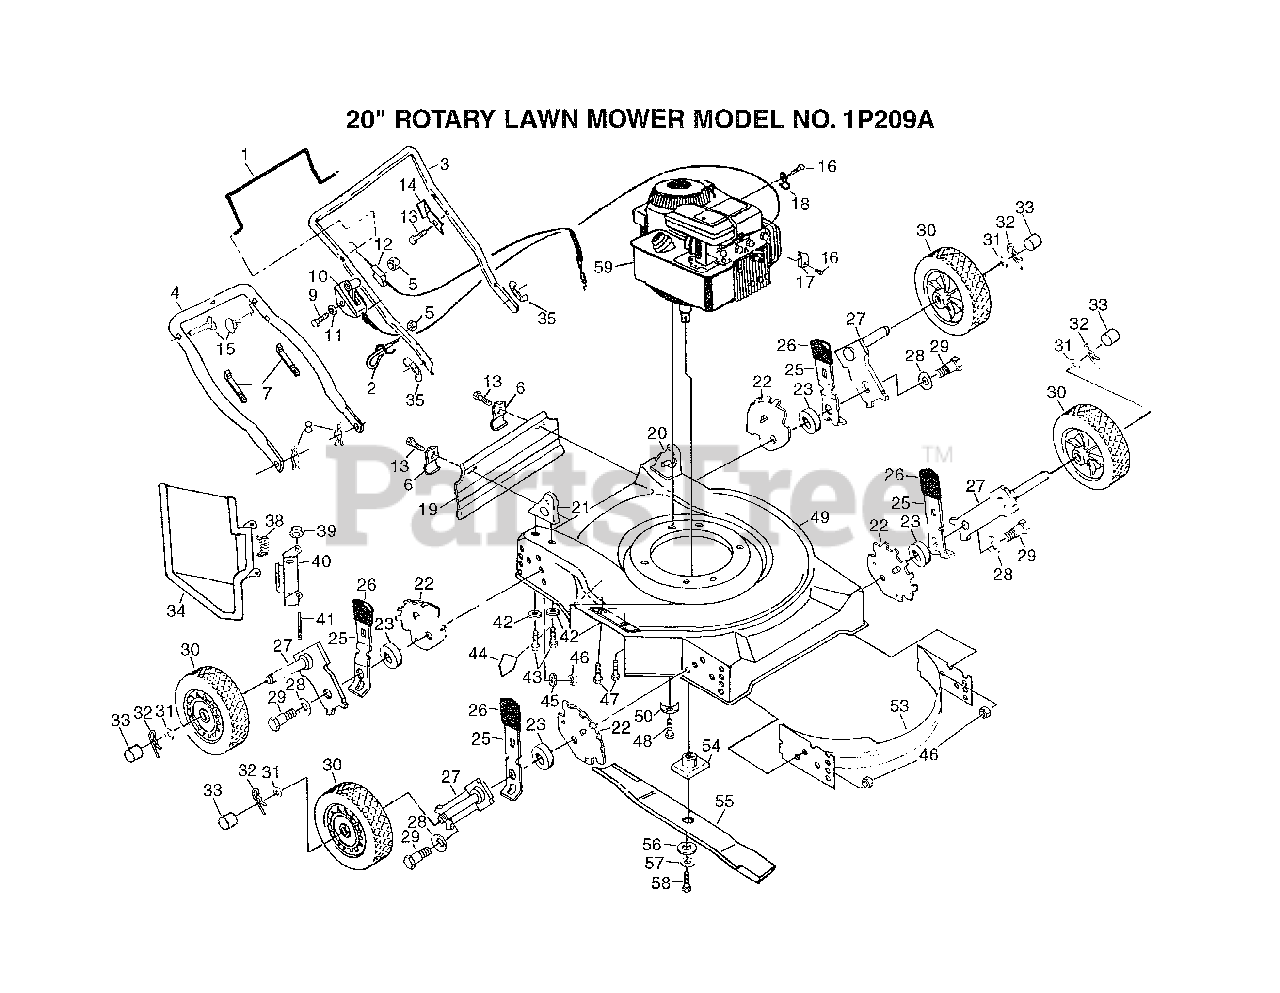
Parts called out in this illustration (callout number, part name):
1	CONTROL BAR PM
2	ROPE GUIDE
6	"BRKT,DEFL PM"
8	HAIRPIN COTTER
10	CONTROL THROTTLE
11	WASHER PM
12	"CABLE,ENG ZONE CO"
13	TAPPING SCREW
14	"BRKT,UPSTOP"
15	BOLT.HANDLE.LM
16	SCREW PM
17	CABLE CLAMP
18	GUIDE CLIP PM
22	BRACKET.WHL.ADJ.9
25	SPRING SELECTOR
26	KNOB PM
27	AXLE ARM
28	"WASHER, BELLEVIL."
30	WHEEL&TIRE
31	WASHER
32	RETAINER CLIP PM
33	HUB CAP-PLASTIC
34	"GRD,DISCHARGE"
35	"NUT,WING PM"
38	"SPRING,TORSION"
39	PUSH ON SPEED NUT
40	"BRKT,HSG "
42	STEEL WASHER
43	SCREW
44	DECAL HYT
46	LOCKNUT PM
47	SCREW
48	SCREW
49	"KIT.HSG.20""SDPUSH"
54	BLADE ADAPTOR
55	BLADE.STAND.20INC
56	"WASHER,HARDEN"
57	LOCKWASHER
58	SCREW
